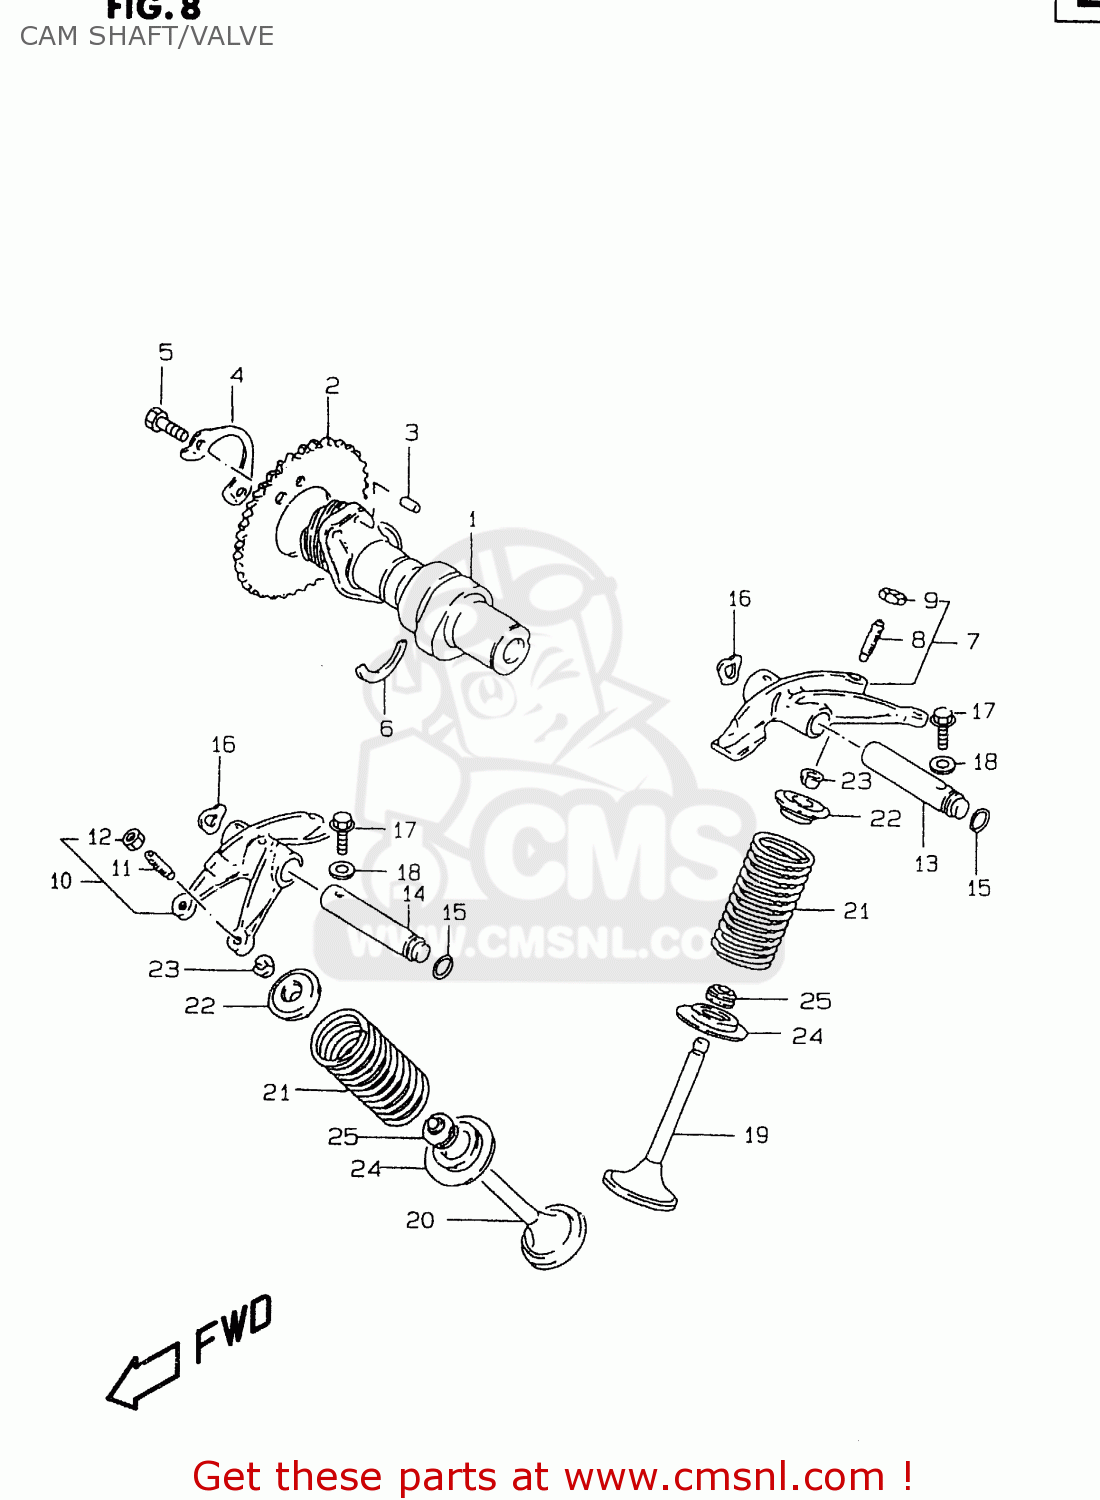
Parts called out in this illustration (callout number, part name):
1	CAMSHAFT
2	SPROCKET,CAMSHAFT(NT:42)
3	PIN
4	WASHER,CAM CHAIN SPROCKET
5	BOLT(6X12.5)
6	C RING
7	ARM,VALVE ROCKER INTAKE
8	SCREW,TAPPET ADJUSTING
9	NUT,TAPPET ADJUSTING
10	ARM,VALVE ROCKER EXHAUST
11	SCREW,TAPPET ADJUSTING
12	NUT,TAPPET ADJUSTING
13	SHAFT,VLV ROCKER ARM IN(L:91.5
14	SHAFT,VLV ROCKER ARM EXH(L:76)
15	O RING(D:1.9,ID:8.6)
16	WASHER
17	BOLT
18	GASKET(5.8X13X1.2) (NAS)
19	VALVE,INTAKE
20	VALVE,EXHAUST
21	SPRING,VALVE
22	RETAINER,VALVE SPRING
23	COTTER VALVE
24	SEAT,VALVE SPRING
25	SEAL,OIL(5.5X11X8.2)
